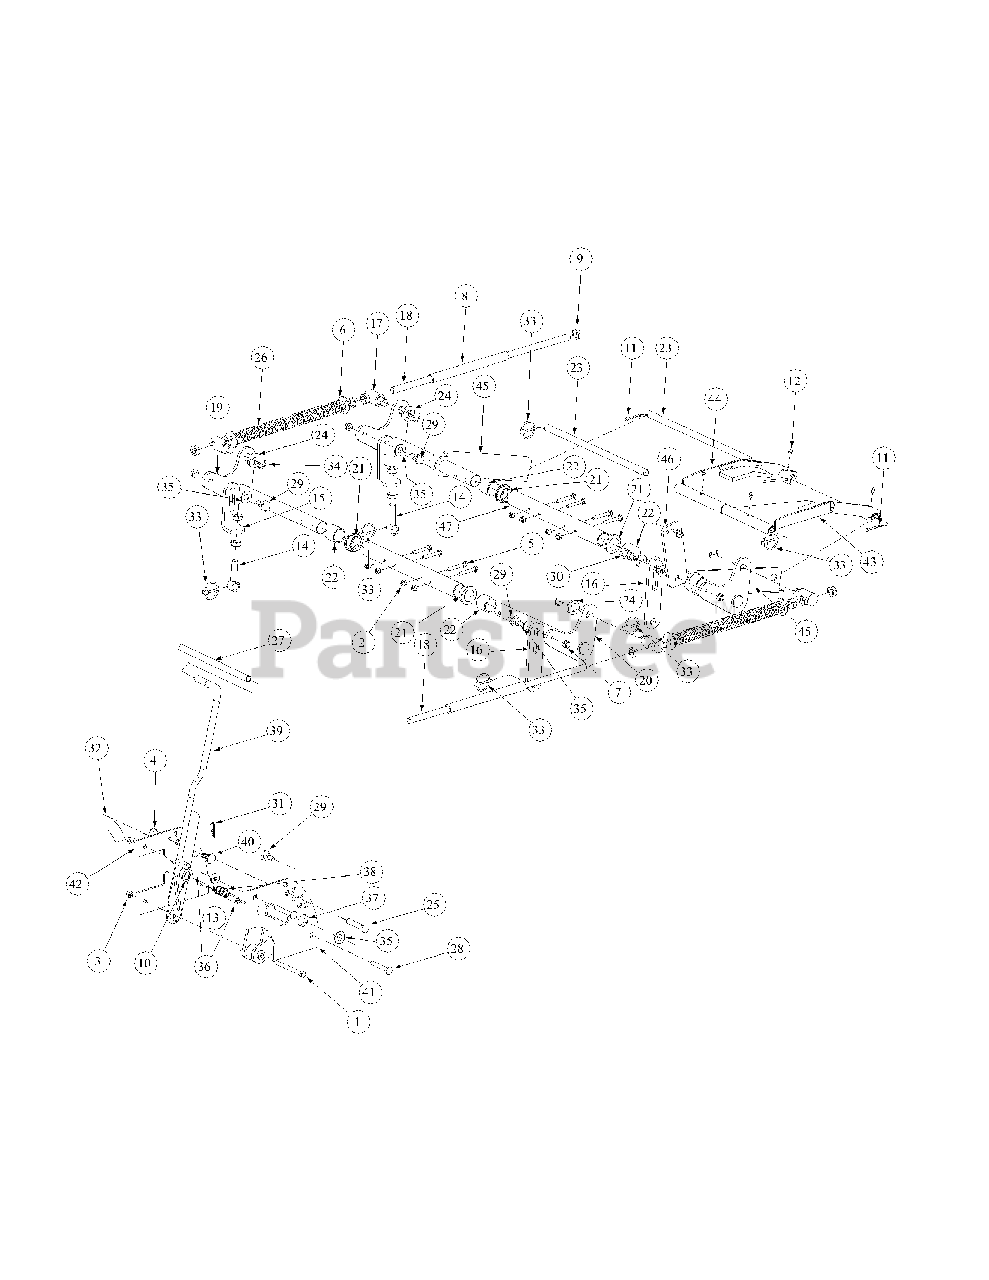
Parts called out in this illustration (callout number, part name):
1	Hex Cap Screw, 3/8-16, 3.75
2	Nut, 5/16-18, Nylock
3	Nylock Insert Lock Nut, 3/8-16
4	Nylock Insert Lock Nut, 1/2-13
5	Hex Cap Screw, 5/16-18 x 2
6	Flat Washer, 5/8
7	Hex Nut, Flange Lock, 3/8-16
8	Hose, 5/8 ID 13/16 OD, 8" LG
9	Jam Nut, 5/8-11
10	Flat Washer, .06, .776, 1.25
11	Cotter Pin, 3/16 x 1-1
12	Grease Fitting, 1/4-28 x 3/16
13	Idler Washer
14	Eye Bolt, 5/8ID
15	Eye Bolt Mount Link, 5/8 ID
16	Deck Link
17	Ferule Lift
18	Lift Connector Rod
19	Bellecrank Weldment Lift, Left Hand
20	Bellecrank Weldment Lift, Right Hand
21	Hex Flange Bearing, 1.25 ID
22	Frame Lift Spacer
23	Front Lift Link, Rod Mount
24	Spacer, .812 ID x .268 Lg.
25	Clevis Pin, .500 Dia. x 2.625 Lg.
26	Lift Compression Spring
27	Lift Handle Grip
28	Carriage Bolt, 3/8-16, 2.75
29	Shoulder Screw, 0.625 OD x .437 Lg.
30	Shoulder Screw, 0.625 OD x .830 Lg.
31	Cotter Pin, .148 x 3.00
32	Decal Height Indicator
33	Linch Pin, 3/16 Dia.
34	E Clip, 3/4 Dia.
35	Nylon Flat Washer, 5/8
36	Spacer, .39 ID x .63 OD x 1.442
37	Lift Pivot Assembly
38	Lift Handle Spring
39	Lift Handle Assembly
40	Shoulder Screw, 5/8 OD x 0.264
41	Outer Lift Index Plate
42	Inner Lift Index Plate
43	Bearing Lift Brace Assembly, Right Hand
44	Bearing Lift Brace Assembly, Left Hand
45	Front Frame Strut Assembly
46	Lift Link Adjustment
47	Lift Shaft Holder
